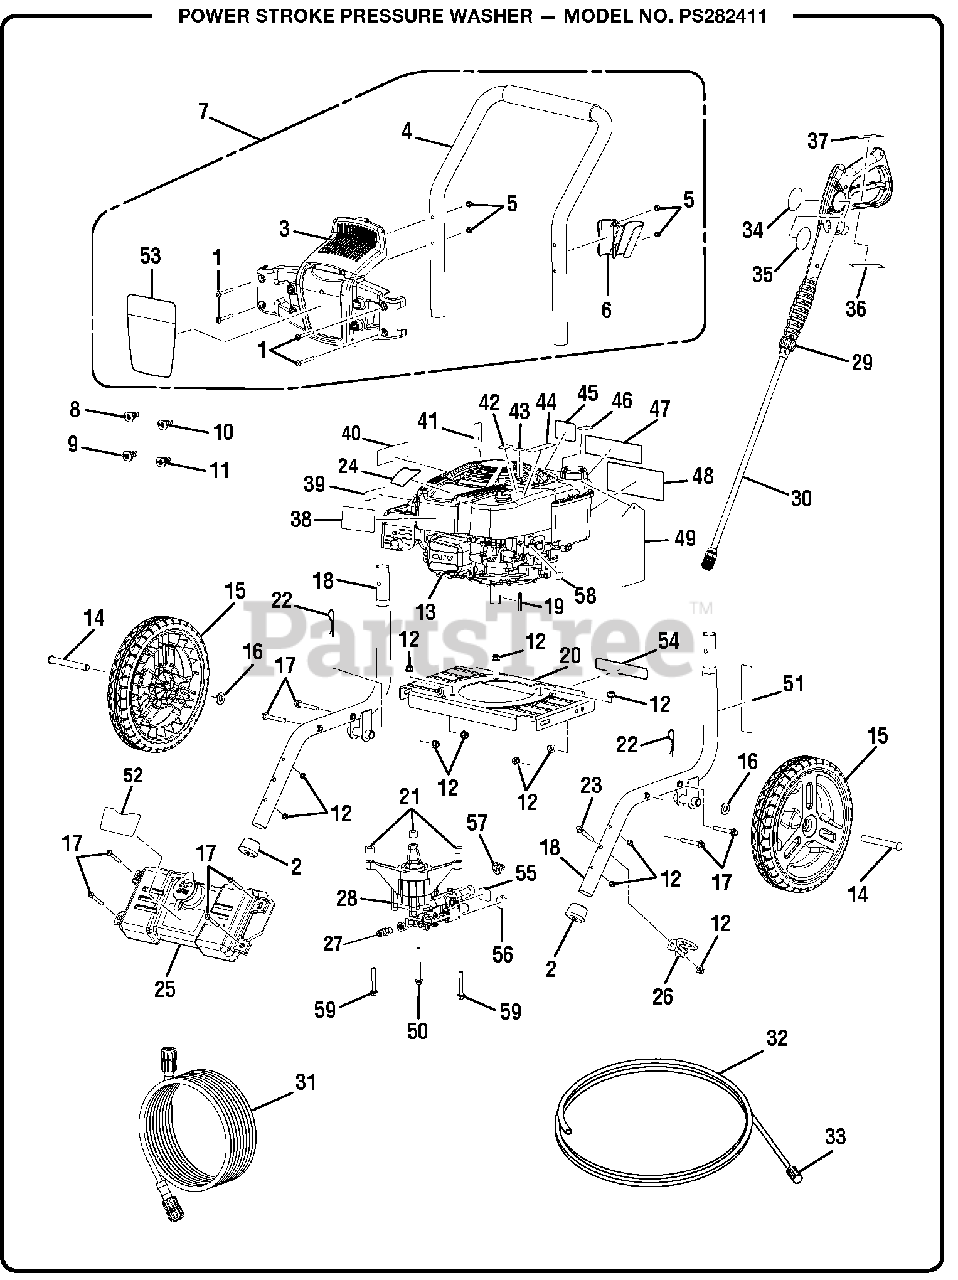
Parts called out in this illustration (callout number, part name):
1	Screw (1/4-20 x 1.85 in., T30 Torx Hd.)
2	Rubber Foot
3	Hose and Nozzle Holder Assembly
4	Handle w/Foam
5	Lock Nut (1/4-20)
6	Wand Holder
7	Handle Assembly
8	40deg Nozzle
9	Soap Nozzle
10	25deg Nozzle
11	0deg Nozzle
12	Flange Nut (M8 x 1.25)
13	Engine
14	Axle
16	Washer (1/2 in.)
17	Bolt (M8 x 55 mm, Flange Hd.)
18	Main Frame Assembly
19	Output Shaft Key (3/16 in. x 40 mm)
20	Engine Plate
22	Axle Retainer Ring
23	Bolt (M8 x 50 mm)
24	Briggs and Stratton Label
25	Soap Tank with Cap
26	Wand Holder Loop
27	Thermal Release Valve
28	Pump
29	Trigger Handle Assembly
30	Extension Wand
31	Hose (25 ft., 3000 psi)
32	Chemical Siphon Tube
33	Chemical Siphon Filter
34	Label (Wand Logo)
35	Label (Wand Warning)
36	Fr/Sp Label (Wand Warning)
37	Label (Wand Rating)
38	875 Series Label
39	Hot Surface Label
40	Danger Label
41	Oil Fill Location Label
42	Engine Quick Start Label
44	Inquiries Label
45	Lubricant Label
46	No E85 Label
47	Combustion Label
48	Costco Label
49	Danger Hang tag
50	Bolt (M8 x 95 mm)
51	Pump Quick Start Label
52	Soap Tank Label
53	Performance Label
54	Data Label
55	Garden Hose Hang Tag
56	High Pressure Hose Hang Tag
57	Filter Screen (Pump Inlet)
59	Bolt (M8 x 70 mm)
